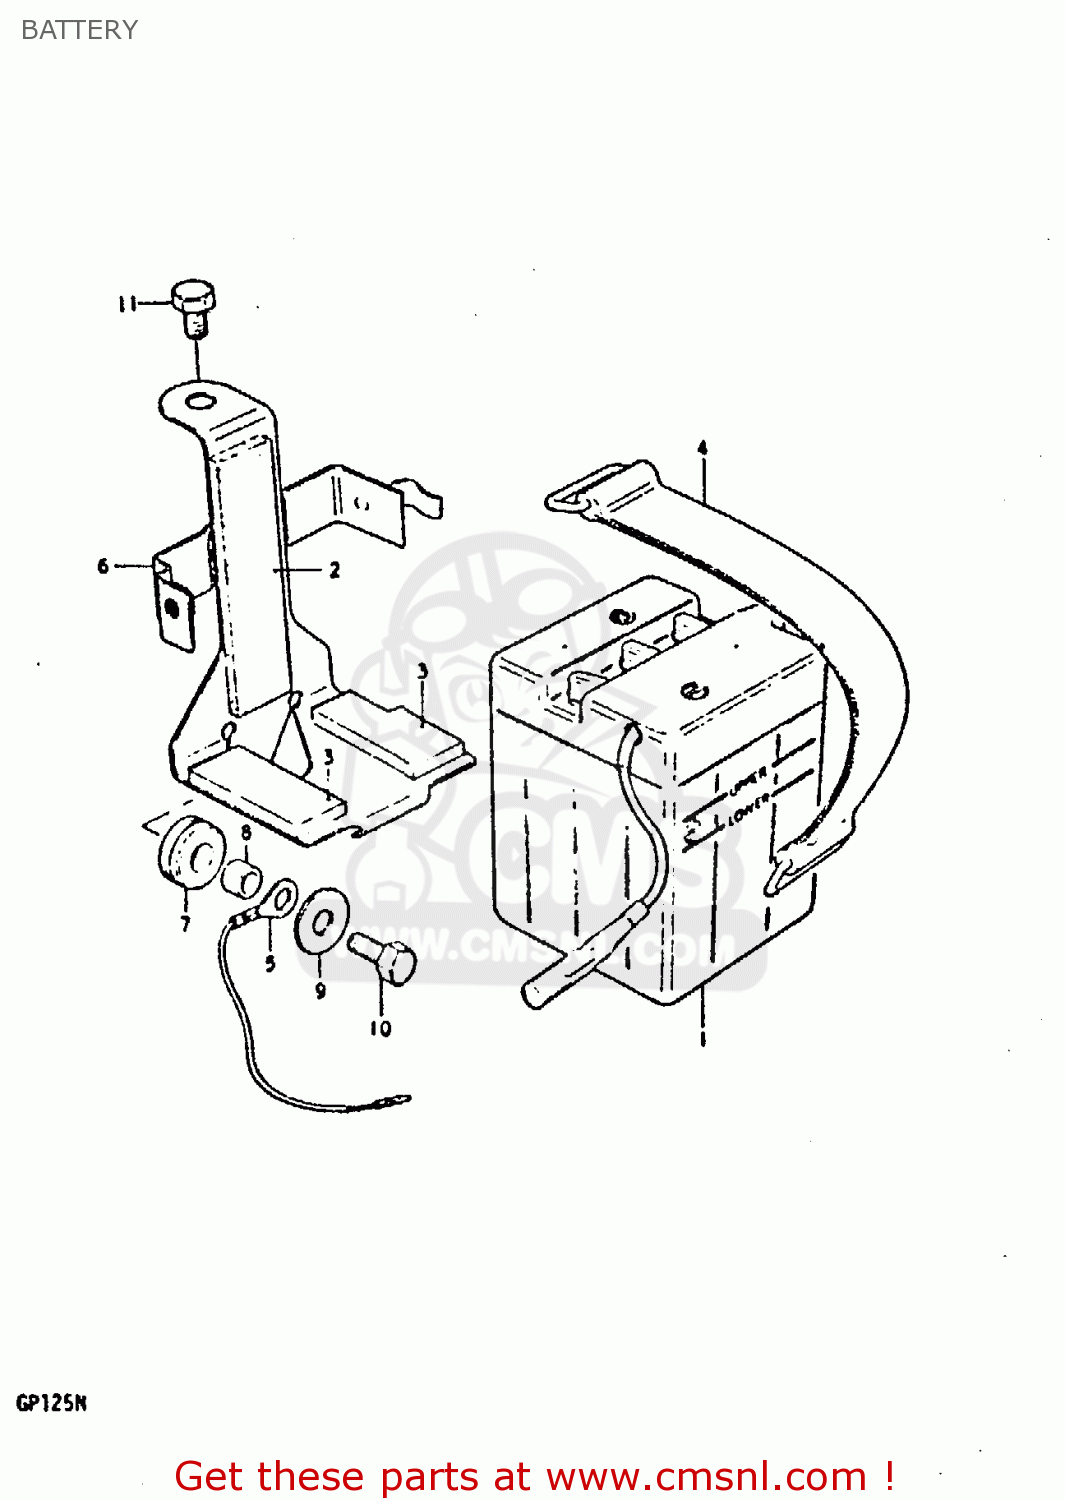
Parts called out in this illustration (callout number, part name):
1	BATTERY ASSY(6N4-2A4.2AH)
2	PROTECTOR,20X9
3	CUSHION 20X45X6
4	BAND
5	LEAD WIRE
6	HOLDER,BATTERY
7	CUSHION
8	SPACER(6.1X9X7.5)
9	WASHER
10	BOLT, UPPER
11	BOLT
